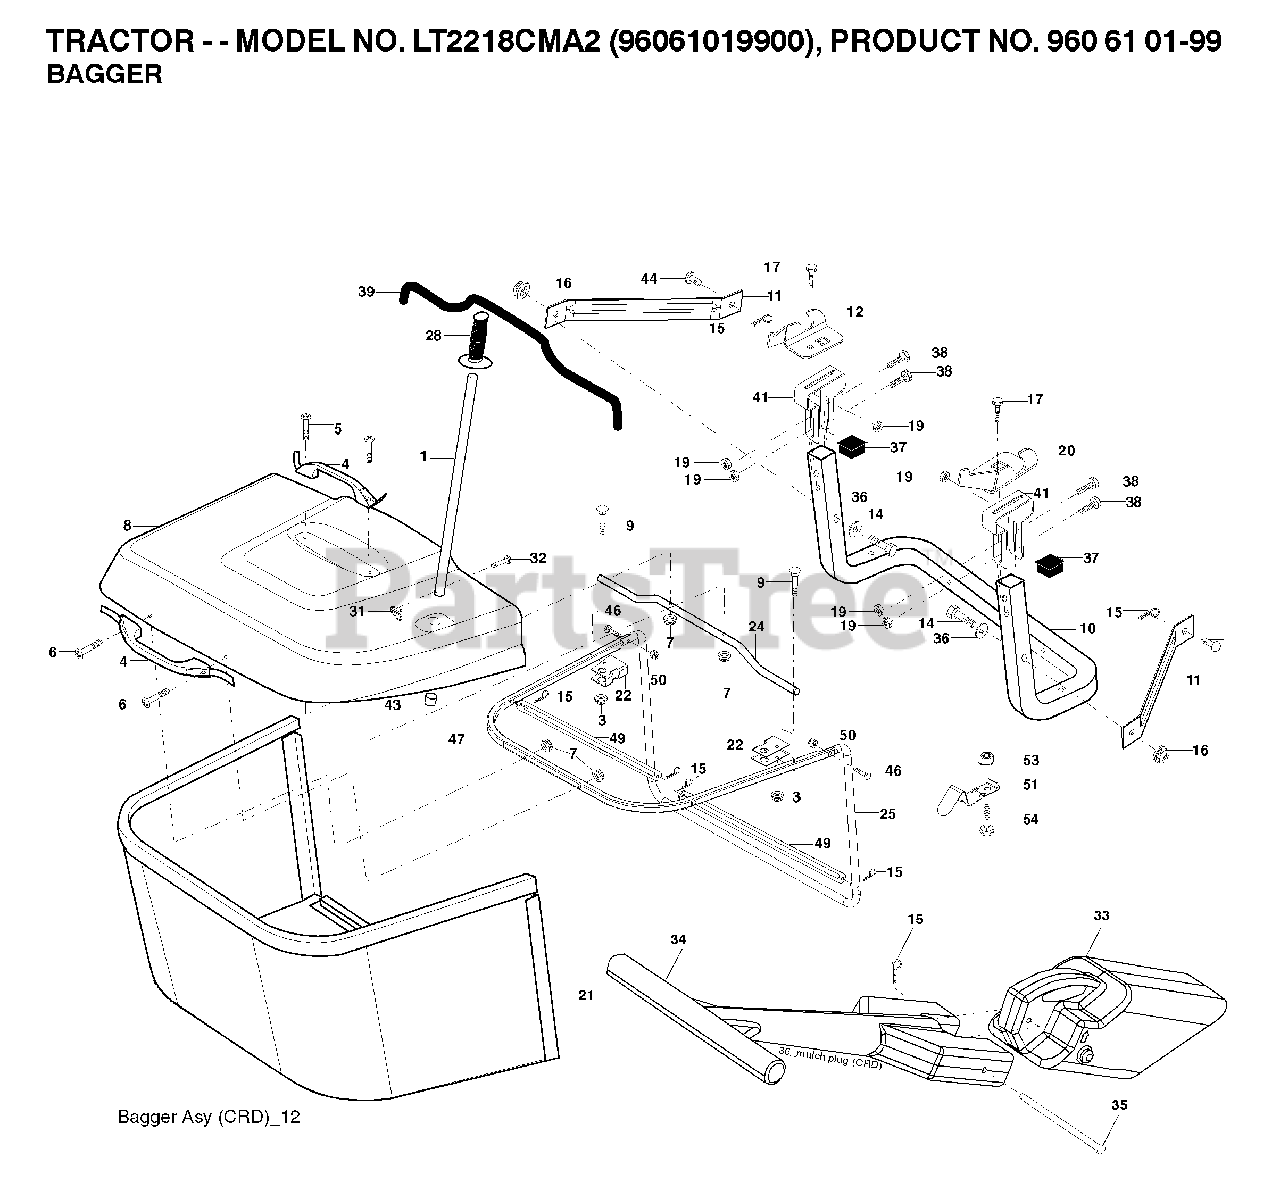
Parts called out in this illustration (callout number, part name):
1	TUBE HANDLE
3	NUT T
5	SCREW.PAN.HEAD
11	BRACKET
14	BOLT-HEX EAK
15	RETAINER-SPRNG RB
16	NUT LOCK FLG 3/8-16 UNC
17	BOLT
19	NUT LOCK HEX FLANGE 5/16-18
20	BRKT.PIVOT.RH.CRD
21	BAGGER.ASM.CRD.2007
22	BRACKET
24	TUBE
28	GRIP.HANDLE.BLACK
31	RETAINER CLIP
32	RIVET,DRILLED
33	MULCH PLUG, CTH150
35	PIN
38	BOLT.5/16-18X2.5
41	BRKT, BAGGER
43	PLUG, TUBING END
46	BOLT.CARRIAGE.5/16-18
50	NUT.71038.31-18.HEX.NYLOCK
53	NUT
54	BOLT
